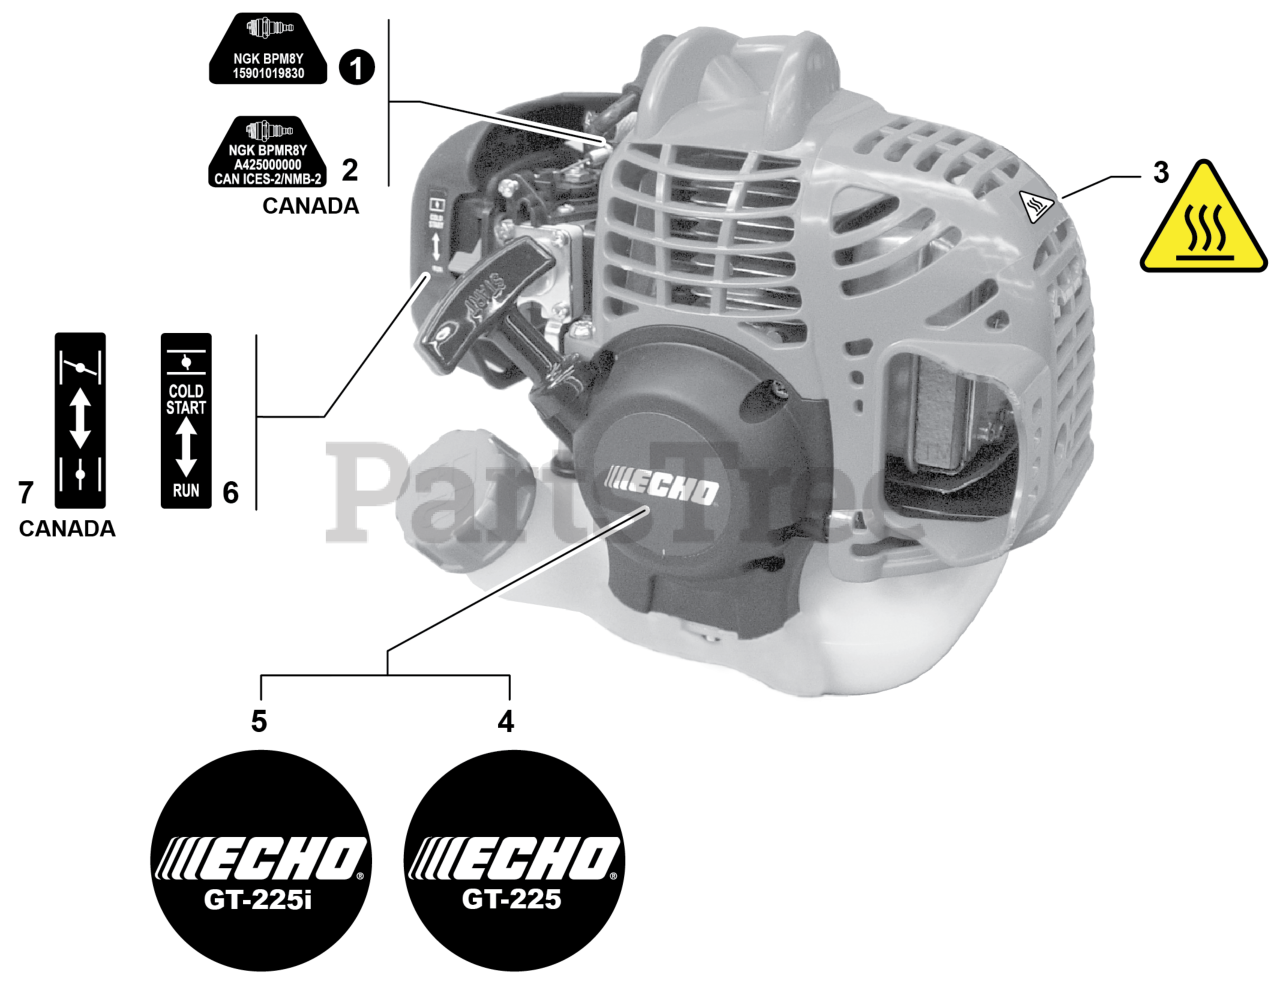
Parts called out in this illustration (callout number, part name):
1	LABEL - SPARK PLUG - BPM8Y
2	LABEL - SPARK PLUG - BPMR8Y
3	LABEL - CAUTION - HOT
4	LABEL - STARTER - GT-225
5	LABEL - STARTER - GT-225I
6	LABEL - CHOKE
7	LABEL - CHOKE
